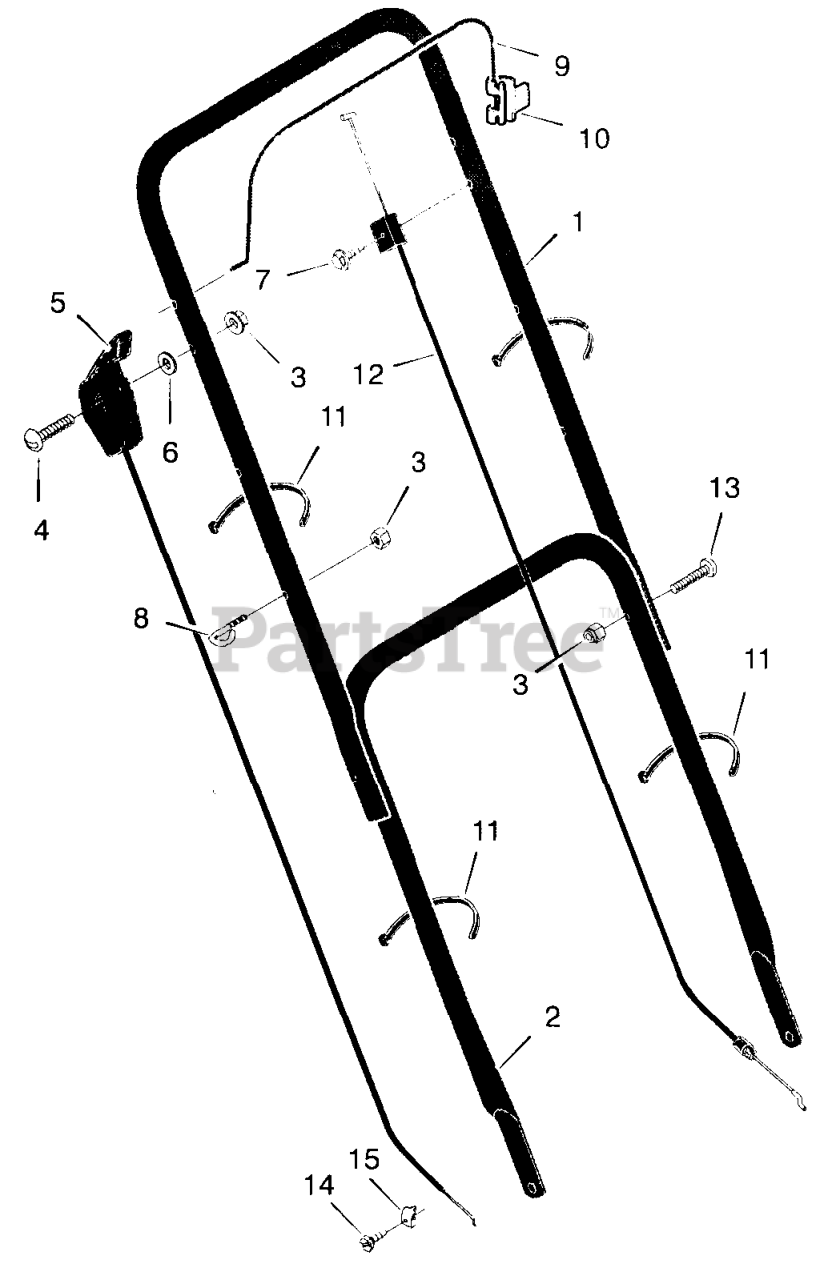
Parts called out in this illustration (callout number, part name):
1	Handle, Upper (Black)
2	Handle, Lower (Black)
3	Locknut
5	Throttle Control
8	GUIDE, ROPE
9	Lever, Engine Stop
10	Bracket, Stop Lever
11	Fastener, Cable
12	Engine Stop Cable
